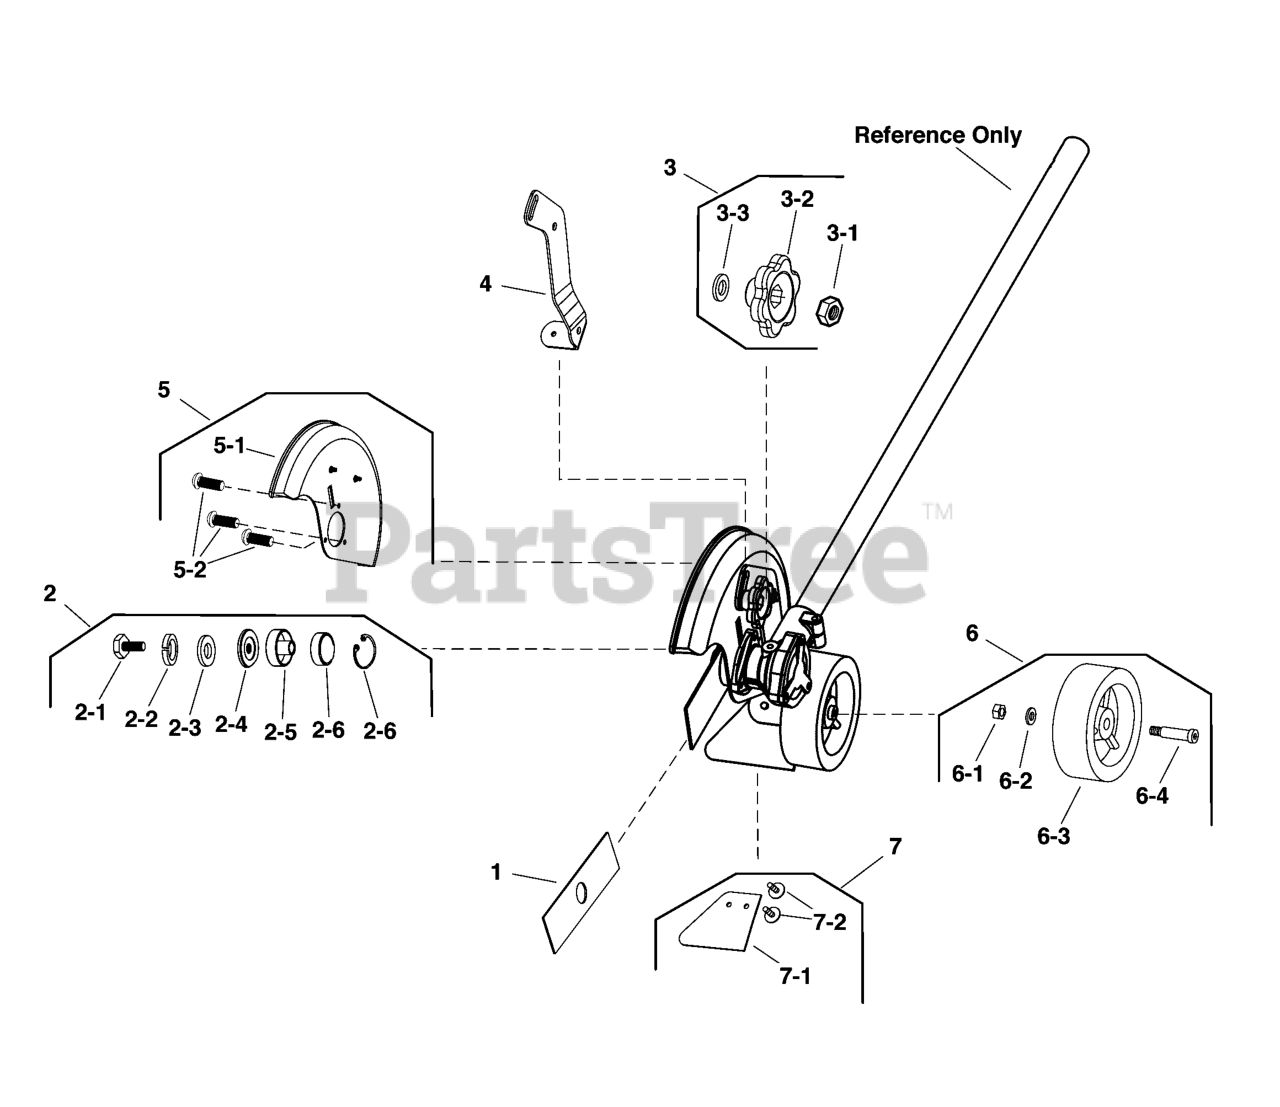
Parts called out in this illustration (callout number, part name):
1	BLADE, Edger
2	KIT, Hardware, Blade
2-4	WASHER, Spline
2-5	BLADE, Insert
3	KIT, Knob, Guard
3-2	KNOB
4	HEIGHT ADJUST, Blade
5	KIT, Guard, Blade
5-2	GUARD, Blade
6	KIT, Wheel
6-3	WHEEL
7	KIT, Guard
7-1	GUARD, Blade
7-2	RIVET, Push-In
